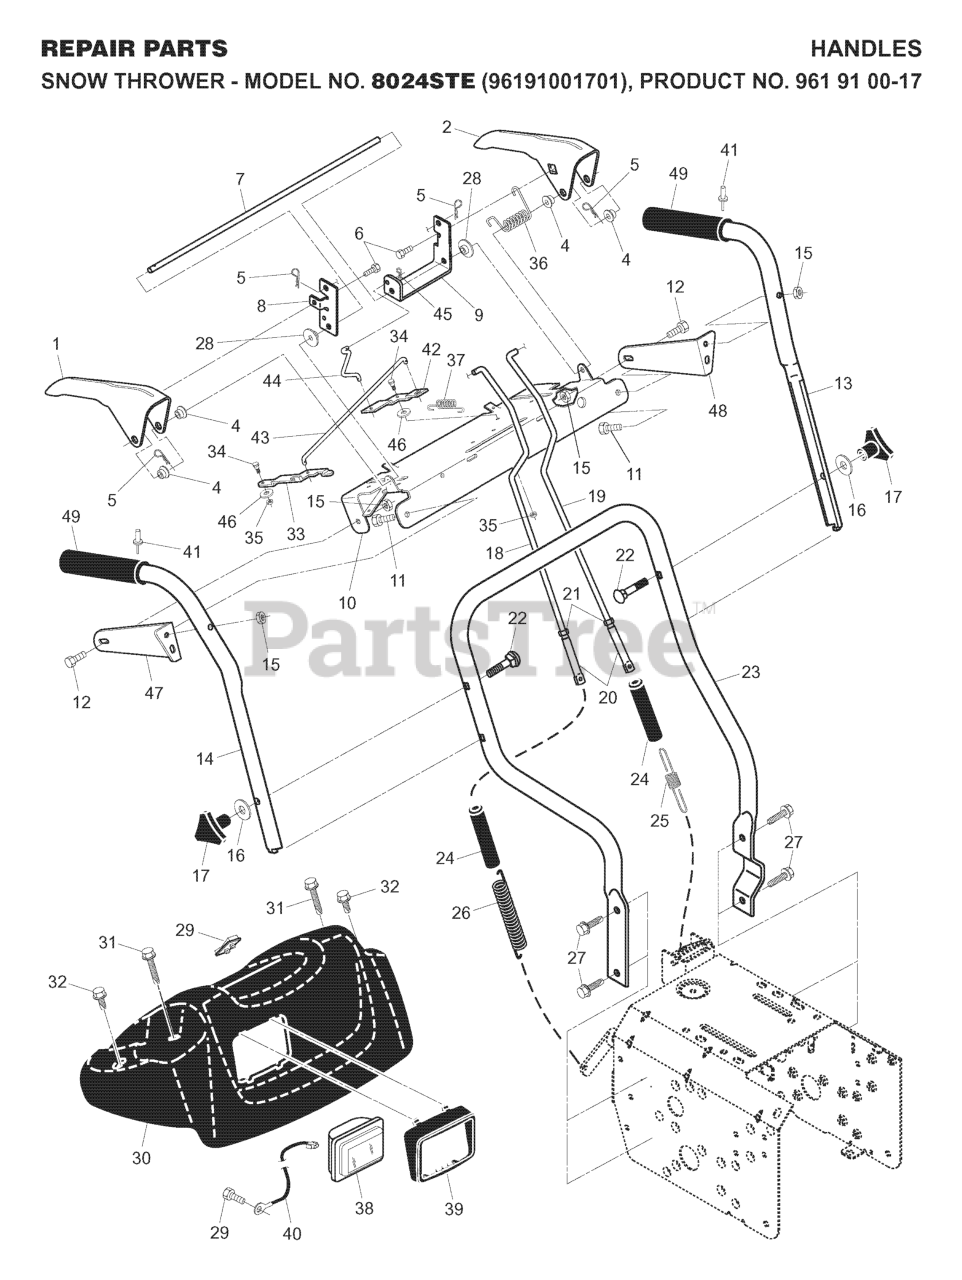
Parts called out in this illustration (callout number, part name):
1	LEVER, AUGER CONTROL, RH
2	LEVER, TRACTION DRIVE CONTROL,
4	BUSHING, FLANGE
5	SPRING RETAINER
7	ROD.INTERLOCK
8	ARM IMPELLER ARM
9	ARM,TRACTION ROD
10	PANEL.CONTROL
11	HEX BOLT
12	BOLT.FIN.HEX.5/16-18X3/4
13	TUBE.HANDLE.PLOW.LH.PNT
14	TUBE.HANDLE.PLOW.RH.PNT
15	NUT.LOCK.5/16-18
16	WASHER
17	KNOB.HANDLE.3/8.TRI-POINT.BLAC
18	ROD.AUGER.CONTROL
19	ROD.CABLE.TRACTION.LONG
20	ROD, END CONTROL
21	JAM NUT TI
22	BOLT 3/8-16 X 2-1/4
23	TUBE.LOWER.HANDLE.24.BLACK
24	SLEEVE, SPRING
25	SPRING, TRACTION DRIVE
26	SPRING, AUGER CONTROL
27	SCREW 3/8-16X1
28	SPACER CONTROL LEVER
29	Screw, Grounding
30	CONSOLE, PANEL
31	SCREW, HEX HD TAPPING #10-24 1
32	SCREW, HEX HEAD, TAPPING
33	LATCH.INTERLOCK
34	BOLT SHOULDER
35	NUT **
36	RP SPRING, TORSION
37	SPRING LATCH
38	HEADLIGHT.HALOGEN.SNOW
39	BEZEL.HEADLIGHT.BLACK
40	HARNESS.WIRE.LIGHT/GRIP.SNOW
41	RIVET.POP.1/8X
42	LEVER.INTERLOCK
43	ROD.LATCH.INTERLOCK
44	ROD.ASM INTERLOCK
45	RETAINER CLIP
46	THRUST WASHER
47	BRKT.PANEL.RH.INT
48	BRKT.PANEL.LH.INT
49	GRIP.HANDLE.HEATED
50	SWITCH.GRIP.HEATED
